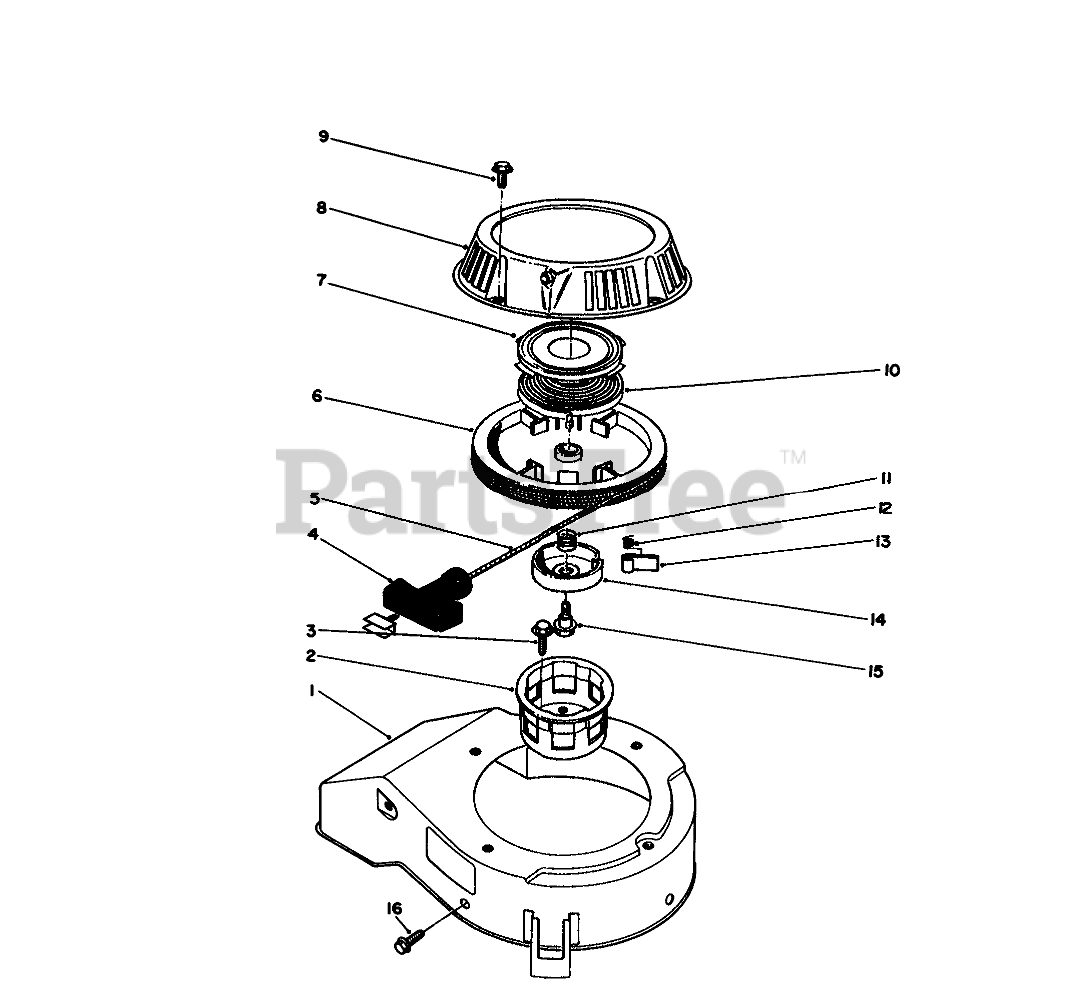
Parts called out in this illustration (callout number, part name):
1	COVER
2	CUP - STARTER
4	HANDLE-RECOIL
5	ROPE-STARTER
7	Retainer-Recoil Spring
9	SCREW-HHF
10	Spring-Recoil
11	SPRING
12	SPRING
14	RETAINER
